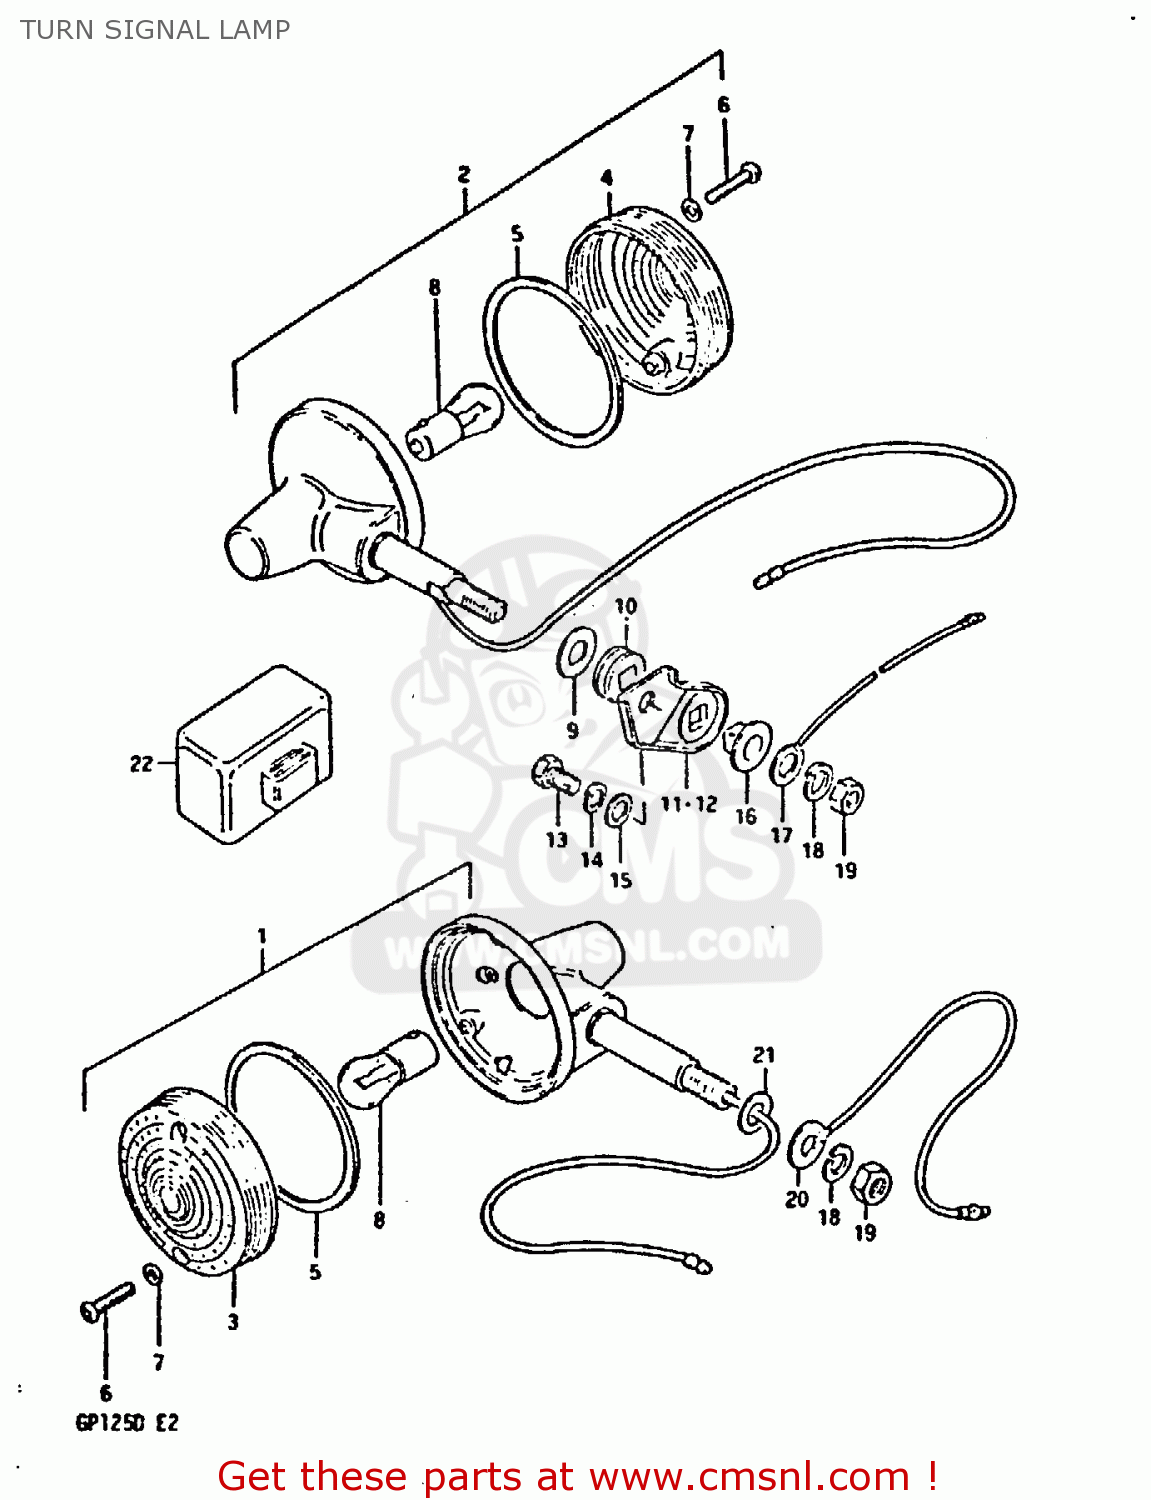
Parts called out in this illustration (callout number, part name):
1	LAMP, REAR TURN SIGNAL
2	LAMP ASSY,RR T
3	LENS
4	LENS
5	GASKET (NAS)
6	SCREW
7	GASKET (NAS)
8	BULB (6V,18W)
9	WASHER (10.5X30X2.3)
10	CUSHION
11	BRACKET, REAR RH
12	BRACKET,RR TURNSIGNAL LAMP,L
13	BOLT
14	LOCK WASHER
15	WASHER
16	SPACER
17	LEAD WIRE,EARTH
18	LOCK WASHER
19	NUT
20	LEAD WIRE,EARTH
21	WASHER
22	RELAY,TURN SIGNAL
